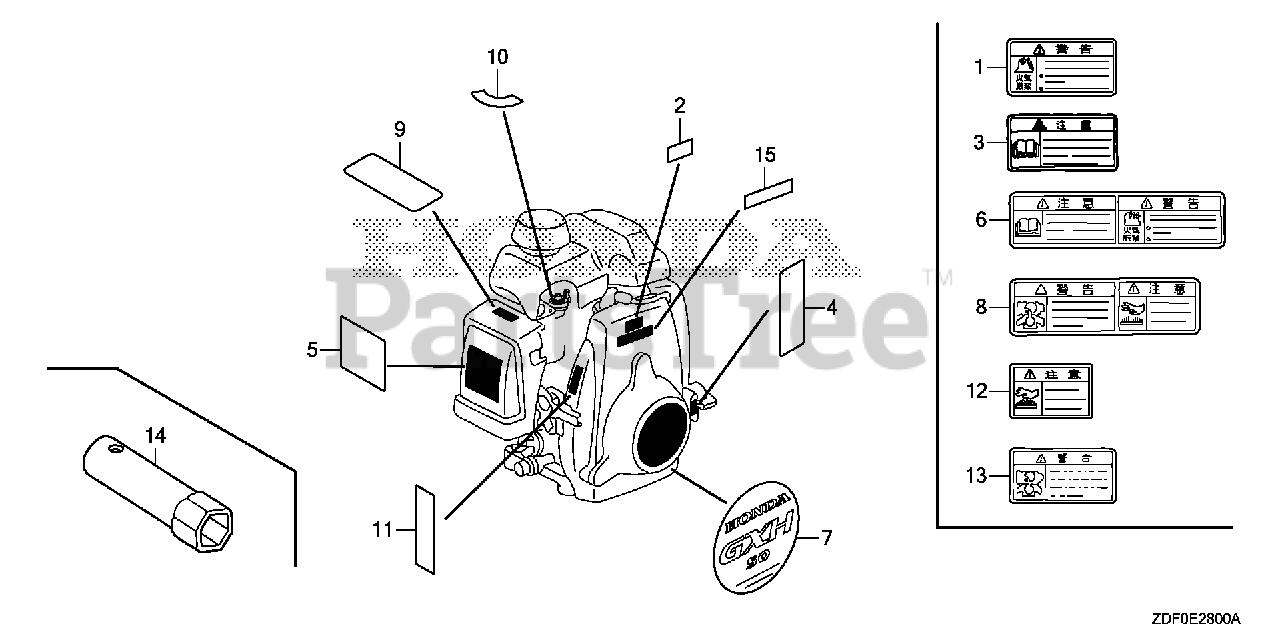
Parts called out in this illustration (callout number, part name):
5	MARK, OPERATOR CAUTION (ENGLISH)
10	MARK, PETCOCK (EXTERNAL)
14	WRENCH, SPARK PLUG
